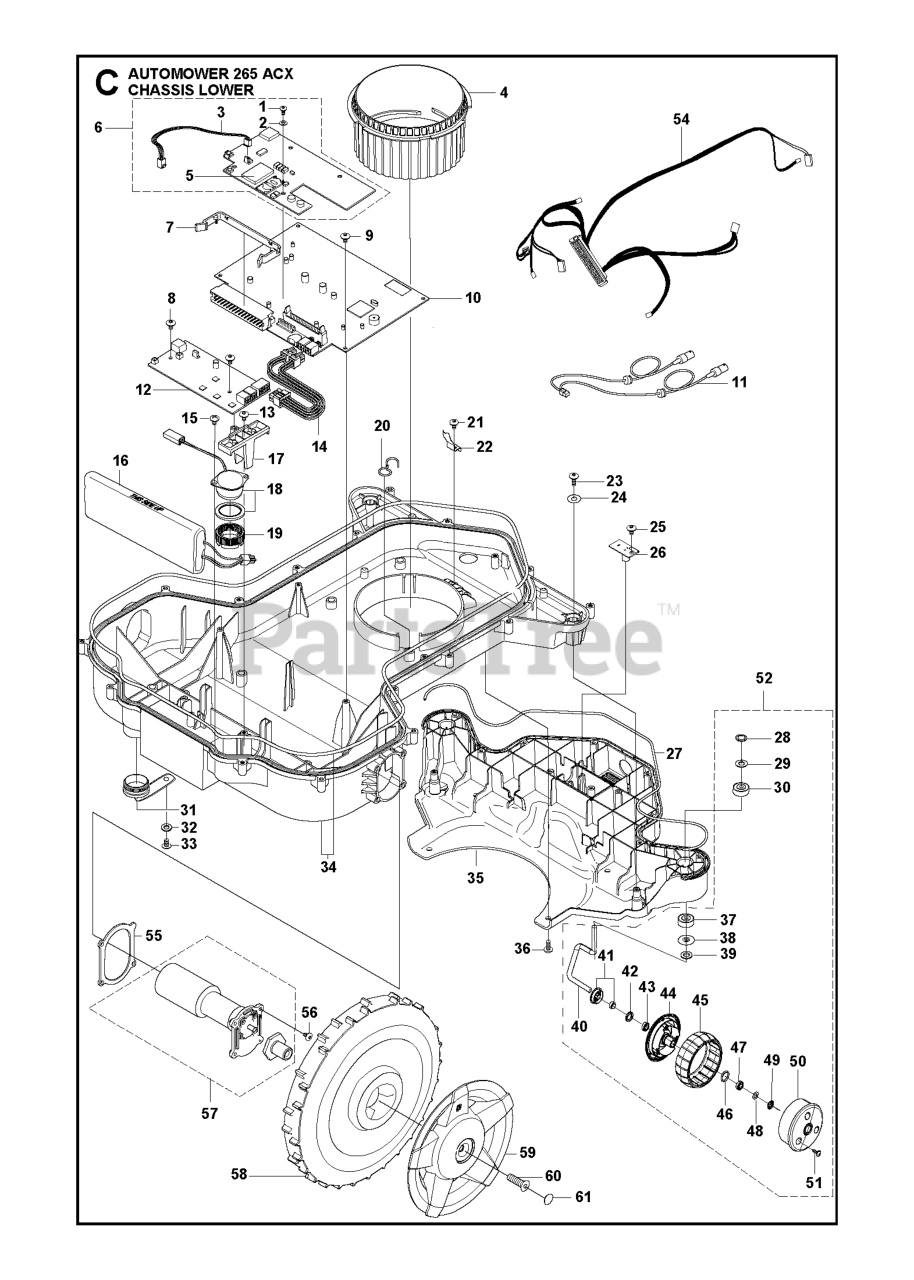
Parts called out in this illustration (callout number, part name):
1	SCREW GSM- MODULE
2	WASHER GSM- MODULE
3	LOOM LOOM GPS TRACKING MODULE
4	CUTTING HEIGHT NUT
5	BATTERY GPS TRACKING COMMUNICA
7	CLIP MAIN CONNECTOR
7	CLIP MAIN CONNECTOR 50PCS
8	SCREW 12MM
9	SCREW SILVER 10MM
13	SCREW 14MM
19	NUT BUZZER
22	LOCKING SPRING
23	SCREW 14MM
25	SCREW SILVER 10MM
28	LOCK WASHER PUSH-ON TYPE P 8 S
29	WASHER 16 OD X 6.5 ID X 1MM
29	WASHER DIN 988 13X8X0.5
31	PLUG SERVICE PLUG
33	SCREW 14MM
36	SCREW 14MM
37	BALL BEARING SINGLE ROW S688
38	WASHER FRONT WHEEL CENTER HOLE
39	WASHER DIN 988 13X8X0.5
41	SHIELD KIT
42	SEALING 12X18X3
43	BALL BEARING SINGLE ROW S688
44	WHEEL FRONT WHEEL INSIDE
45	WHEEL RUBBER TYRE
46	O-RING 2,62X15,54
47	BALL BEARING SINGLE ROW S688
48	WASHER DIN 988 13X8X0.5
49	LOCK WASHER PUSH-ON TYPE P 8 S
50	WHEEL FRONT WHEEL OUTSIDE
51	SCREW 14MM
56	SCREW
57	DRIVE MOTOR
58	REAR WHEEL ASSY 230
60	SCREW
61	COVER WASHER
